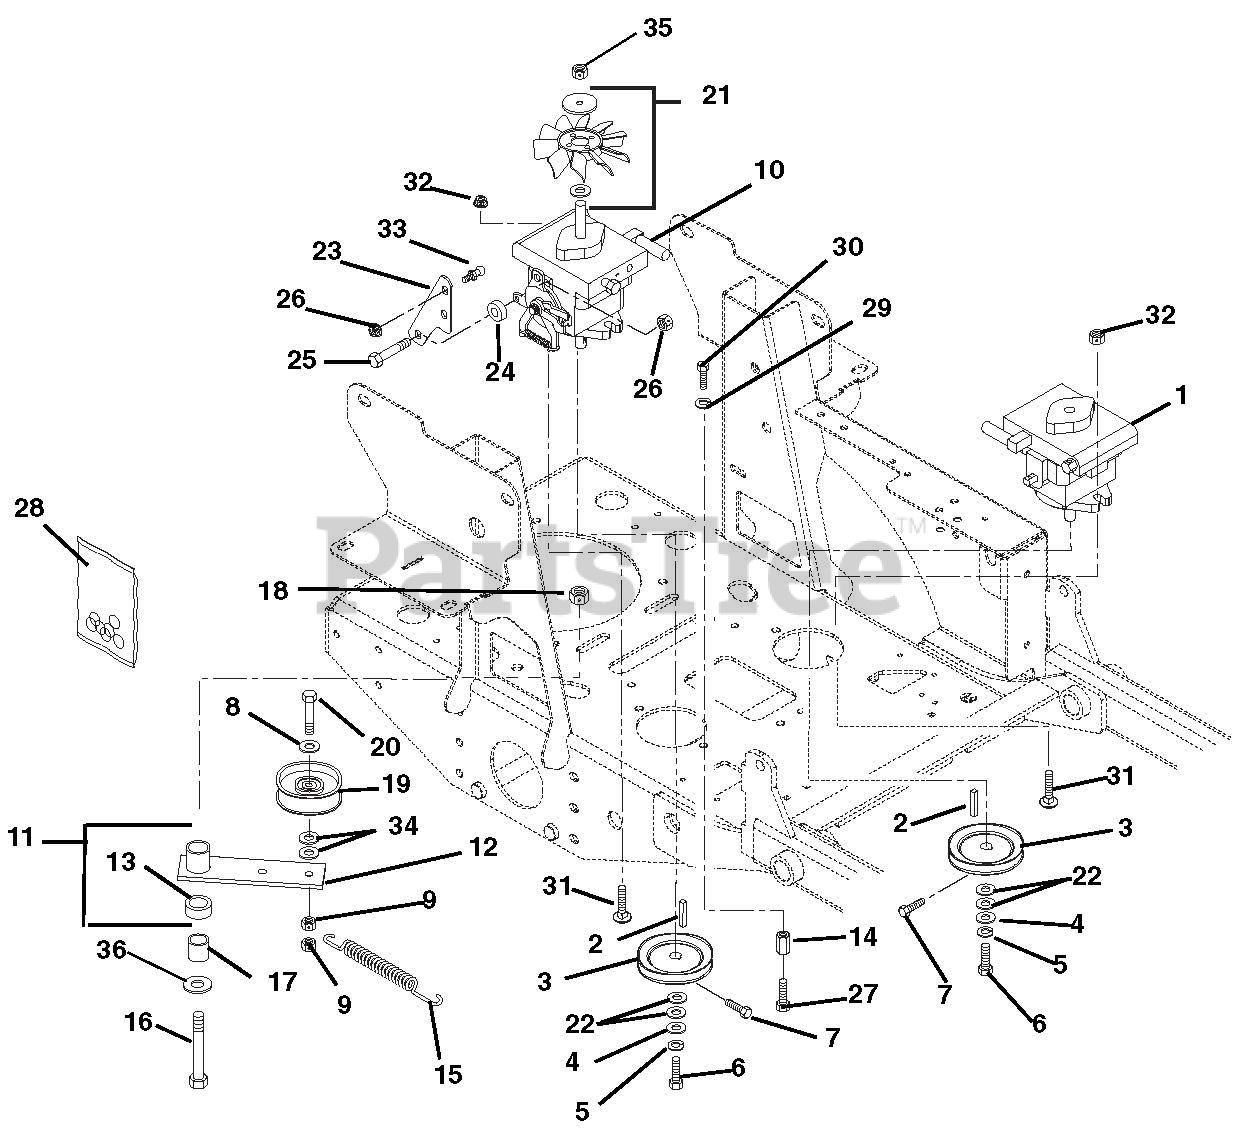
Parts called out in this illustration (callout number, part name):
1	Pump, Hydraulic BDP-10A Left Hand
2	Key, Straight 5mm x 25mm x 5mm
3	Sheave 4.0 x .199
4	Washer, Flat Steel .281 x 1.00 x .063
5	Washer, Locking .25 x .062
6	Bolt, Hex M6 x 1.00 x 12 Epoxy 30
7	Bolt, Hex .25-20 x .50 Grade 5
8	Washer, Flat Steel .406 x .812 x .065
9	Nut, Nyloc Flange .38-16
10	Pump, Hydraulic BDP-10A Right Hand
11	Assembly, Idler Arm Guard Drive
12	Weldment, Idler Arm Ground Drive
13	Bearing, 1.00 x 1.12 x .75
14	Nut, Coupling .375-16 x 1.75
15	Spring, Tension .120 x .845 x 6.50
16	Bolt, Hex .50-13 x 3.75 Grade 5
17	Bushing, Spacer .505/.500 x .999/.996 x 2.05/2.03
17	Bearing, Pedestal
18	Nut, Nyloc Flange .50-13
19	Idler, Flat 4.00 x .38 I.D.
20	Bolt, Hex .38-16 x 2.50 Grade 5
21	Fan, Cooling
22	Washer, Flat Steel .656 x 1.31 x .095
23	Bracket, Return to Neutral/Damper
24	Spacer .344 x 1.00 x .375
25	Bolt, Hex .31-18 x 1.25 Grade 5
26	Nut, Nyloc Flange .312-18
27	Bolt, Hex .38-16 x 1.50 Grade 5
28	Kit, Pump Seal (BDP-10A)
29	Washer, Locking .38 x .094
30	Bolt, Hex .38-16 x .75 Grade 5
31	Bolt, Round Head Square Neck .44-14 x 1.50 Grade 5
32	Nut, Nyloc Flange .44-14
33	Stud, Ball
34	Washer, Flat Steel .406 x 1.00 x .188
35	Nut, Center-Lock .31-24
36	Washer, Flat Steel .511 x 1.441 x .125
